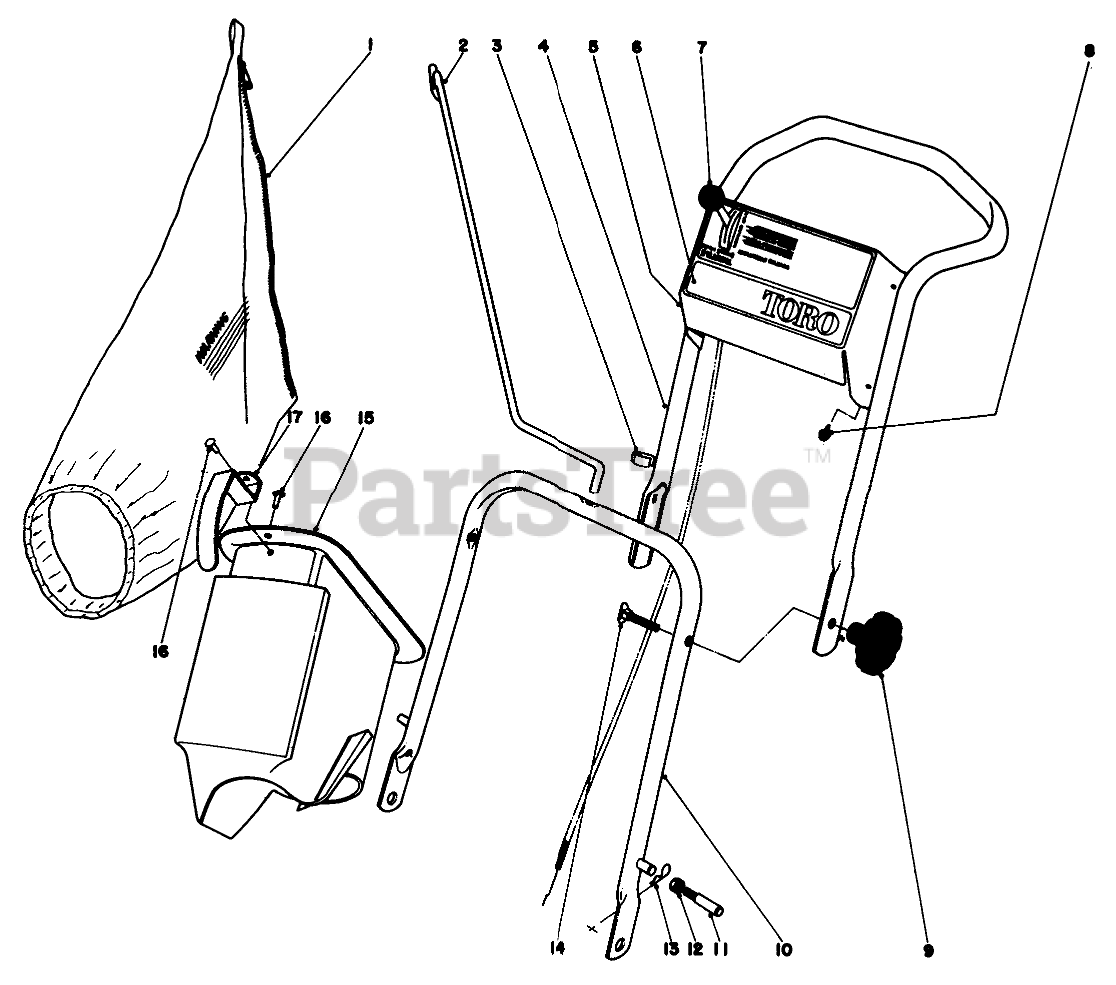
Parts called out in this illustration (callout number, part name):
1	BAG REPLACMNT44-0540
2	Bag Rod
4	UPPER HANDLE
5	Control Plate
6	Decal Control Plate
7	Control Throttle
8	SCREW-HWHTF
10	Lower Handle
11	HANDLE PIN
12	Nut
13	PIN-COTTER, HAIR
14	SCREW-HANDLE
15	Grass Chute (Incl. Ref. No. 16 and 17)
16	RIVET 3/16 X 7/16
17	HANDLE-GRASS CHUTE
